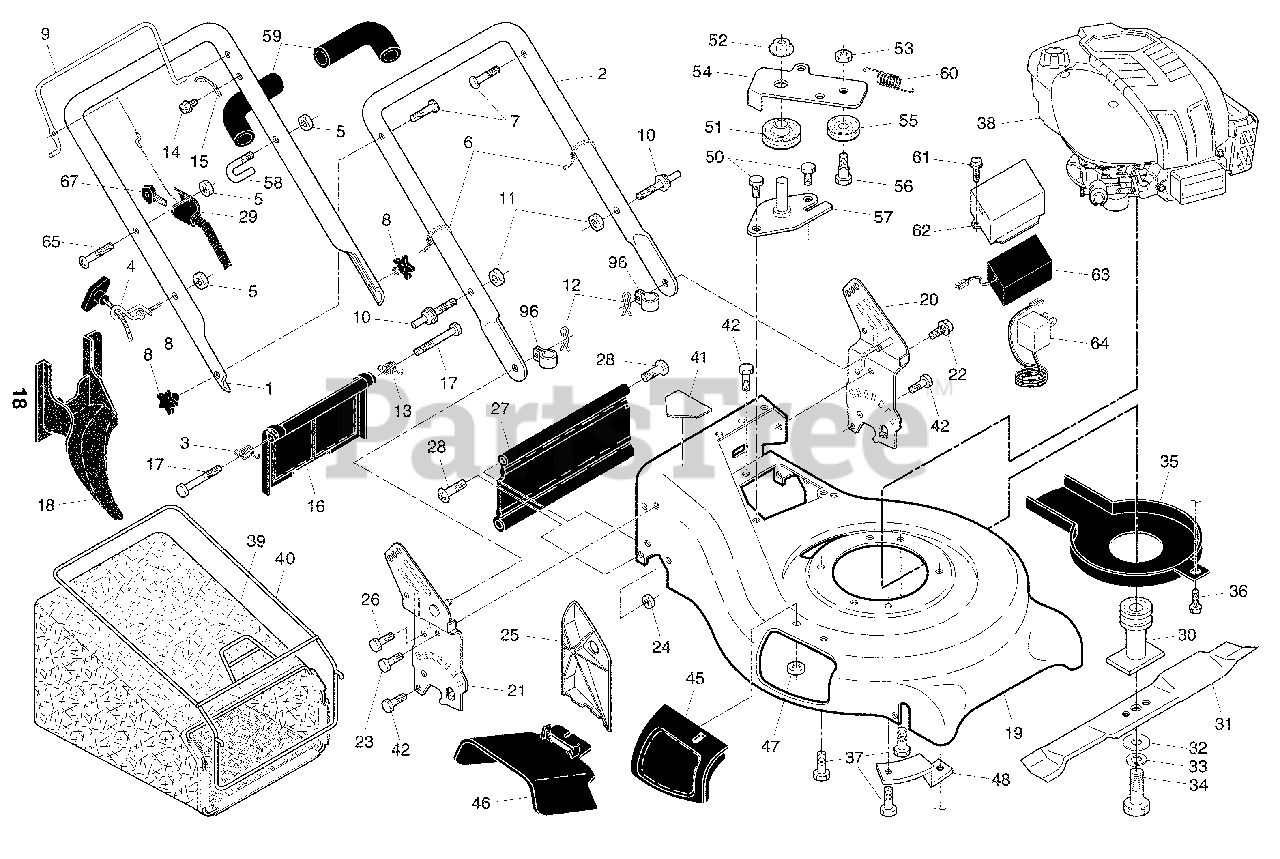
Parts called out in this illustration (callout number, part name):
1	Handle, Upper
2	Handle, Lower
3	Spring, Rear Door, RH
4	Guide, Rope, Side
5	Nut, Hex Lockwasher Insert 1/4-20
6	Wire, Tie
7	Bolt, Handle 5/16-18 x 1.75
8	Knob, Handle
9	Bail, Flat, Auto-Walk, Orange
10	Bolt, Carriage
11	Nut, Hex, Centerlock 5/16-18 UNC
12	Cotter, Hairpin
13	Spring, Rear Door, LH
15	Bracket, Upstop
16	Rear Door Assembly
17	Bolt, Rear Door
18	Plug, Mulcher
19	Kit, Housing
20	Handle Bracket Assembly, LH
21	Handle Bracket Assembly, RH
22	Screw, Hex Washer Head
23	Bolt, Hex Head 5/16-18 x 5/8
24	Nut, Hex, with Lock Washer Insert 5/16-18
25	Baffle, Side
26	Screw 12 x 5/8
27	Skirt, Rear
28	Screw, Hinge 1/4-20 x 1.25
29	Key Start Switch
30	Blade Adapter / Pulley
31	Blade, 21"
32	Washer, Hardened
33	Lockwasher, Helical Spring 3/8
34	Screw, Hex Head 3/8-24 x 1.38
35	Debris Shield
37	Bolt, Engine
39	Grassbag
40	Frame, Grassbag
41	Danger Decal
45	Mulcher Door Assembly
46	Deflector, Discharge
48	Mounting Bracket, Debris Shield
51	Pulley Assembly, V-Groove
52	Flange Nut
53	Locknut
54	Idler Arm
55	Idler Pulley
56	Shoulder Bolt
57	Bracket Assembly
59	Grip, Handle, Foam, Smooth
60	Spring, Return
62	Box, Battery
63	Battery
64	Charger, Battery
96	Clip, Cable
